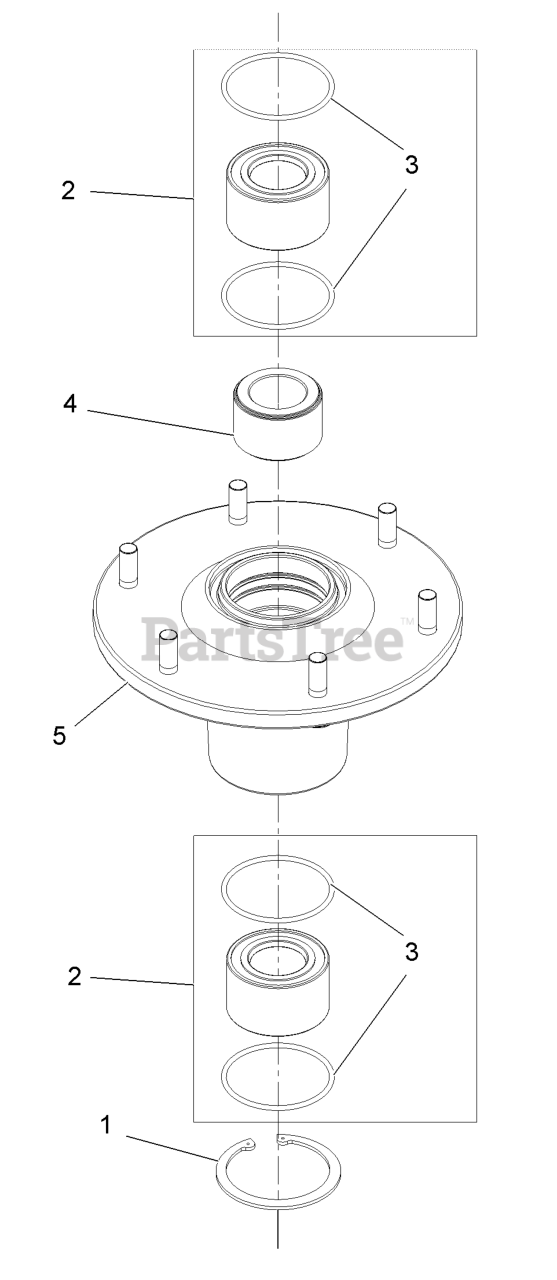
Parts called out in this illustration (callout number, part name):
1	RING-RETAINING
2	ASM, BEARING W/ORINGS
4	SPACER,BEARING
5	ASM,HOUSING W/STUDS
